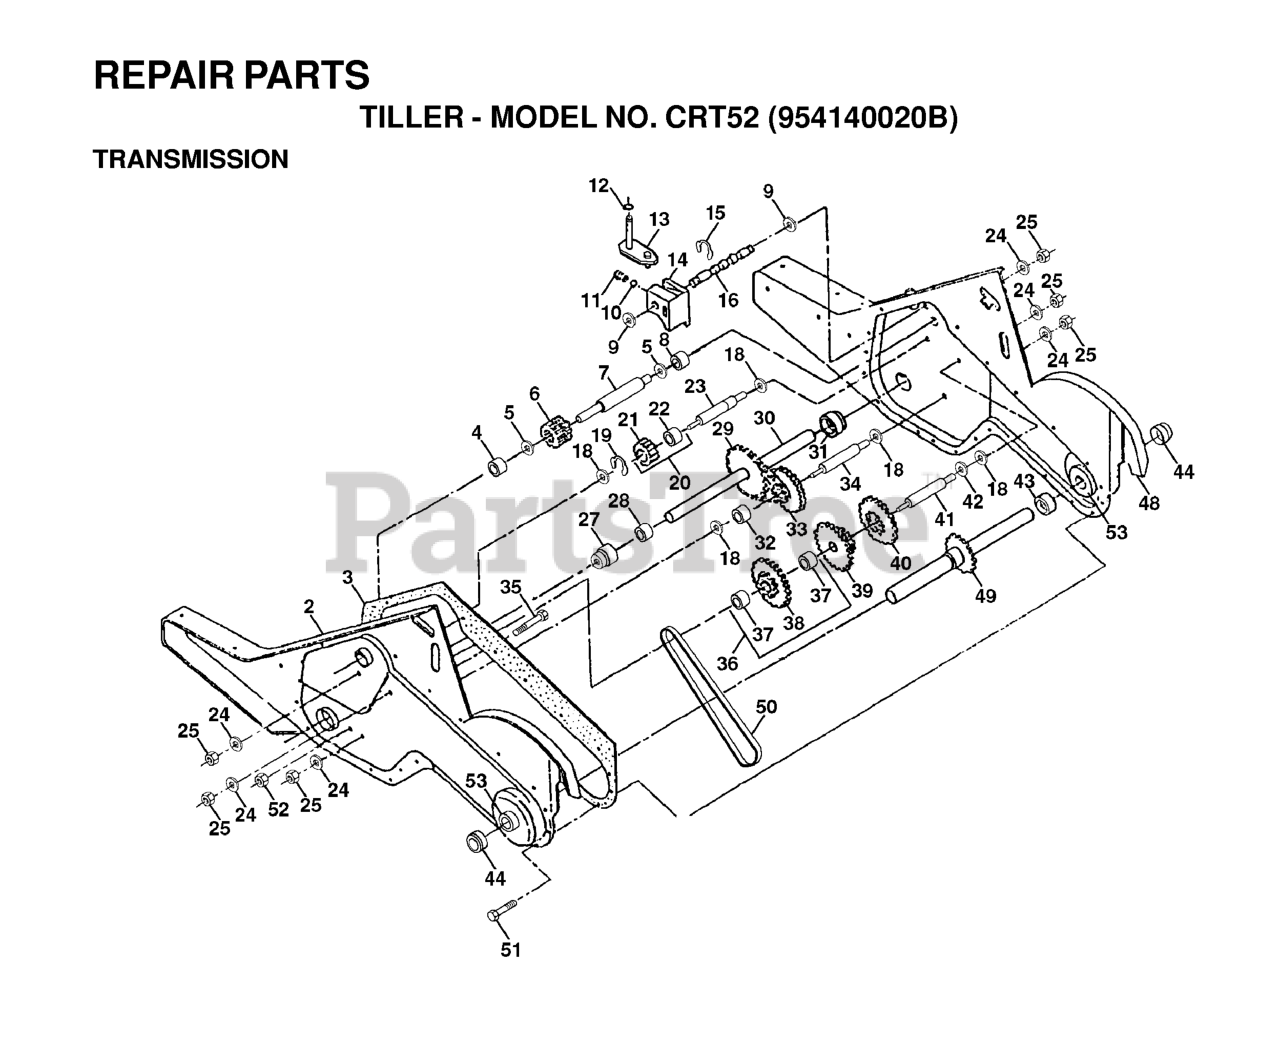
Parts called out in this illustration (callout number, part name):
2	DRAWBAR.STGT
3	APPLIQUE.SUBASM.GT.HUSQ.II
5	DASH.UPPER.ASM.GT2.DR.EL.EFM
14	HOOD.ASM.HUSQVARNA.GT.TEX.ORAN
15	LED LIGHT.LH
18	GRILLE SUBASM.GT.II.LOW.HDLGHT
25	LENS.RH
36	SCREW 5/16"
37	FENDER.PNT.TX.GT.CH/FW/DL.HUSQ
58	BRKT.SUPPORT.FNDR/TANK
68	SCR 5/16-18 X 1/2 SELFTAP ZN
125	CLIP.FUEL.LINE
130	SCREW.#10 X 0.750.BOS
137	BUMPER DASH
146	BOLT.RDHD.SHT.SQNK.3/8-16X5/8
150	AIR.DUCT.GTV.BLACK
151	BRACKET.PIVOT.HOOD.GT.HUSQ.II
152	SHIELD.BROWNING.PNT.GT.V2
159	SCREW, 3/8-16X3/4
161	CONSOLE.WINDOW.FUEL.HUSQ.GT
162	SCREW.HI-LO.CONSOLE
165	SUPPORT.TANK.REAR.B/TE
175	PLATE.PNT.CROSSMEMBER.HUSQ/PRE
176	SCREW.#10-24X5/8.RN.QU
177	BUSHING STEERING
180	CHASSIS LTGT BOLTED PAINTED X4
182	DASH.LOWER.COMMON.12V.ADAPTOR
183	BOLT.5/16-18X1-1/4 FULL THD
189	SCREW
191	INSERT INFLECT.RH
194	NUT LOCK HEX FLANGE 5/16-18
196	CONSOLE.ASM.DECKLIFT.HUSQGT.DL
199	PLATE.DECK.LIFT.HUSQVARNA.GT
202	VENT.SIDE.RH.GT.HUSQ.II.
203	VENT.SIDE.LH.GT.HUSQ.II.498
204	VENT.TOP.HUSQ.GT2
205	SIDE.TRIM.RH.GT.HUSQ.II
206	SIDE.TRIM.LH.GT.HUSQ.II.GRAY
207	BEZEL GT2 LED RH W/ LOWER.ATT
208	BEZEL GT2 LED LH W/ LOWER ATT
214	CLIP.RETAINER.TINNER.
217	ROD.PIVOT.HOOD
221	REFLECTOR.LH.TEX GT HU
228	STUD.FASTNER.W/ANTI-ROTATE
235	SPACER FENDER
236	NUT.CENTERLOCK.5/16-
281	SCREW 3/8-16X1
296	LED LIGHT.LH
297	INSERT REFECT LH
299	LED LIGHT.RH
306	NUT LOCK FLG 3/8-16 UNC
335	COVER.LOWER.DASH.RH.BLACK
336	COVER-LH.LOWER.DASH.GT2.BLACK
350	KIT GUARD BRUSH
375	BUMPER CLIP-ON. DASH 1"
378	BUSHING FLANGE; PLASTIC
379	CHASSIS.PLATE.REINFORCEMNT.431
